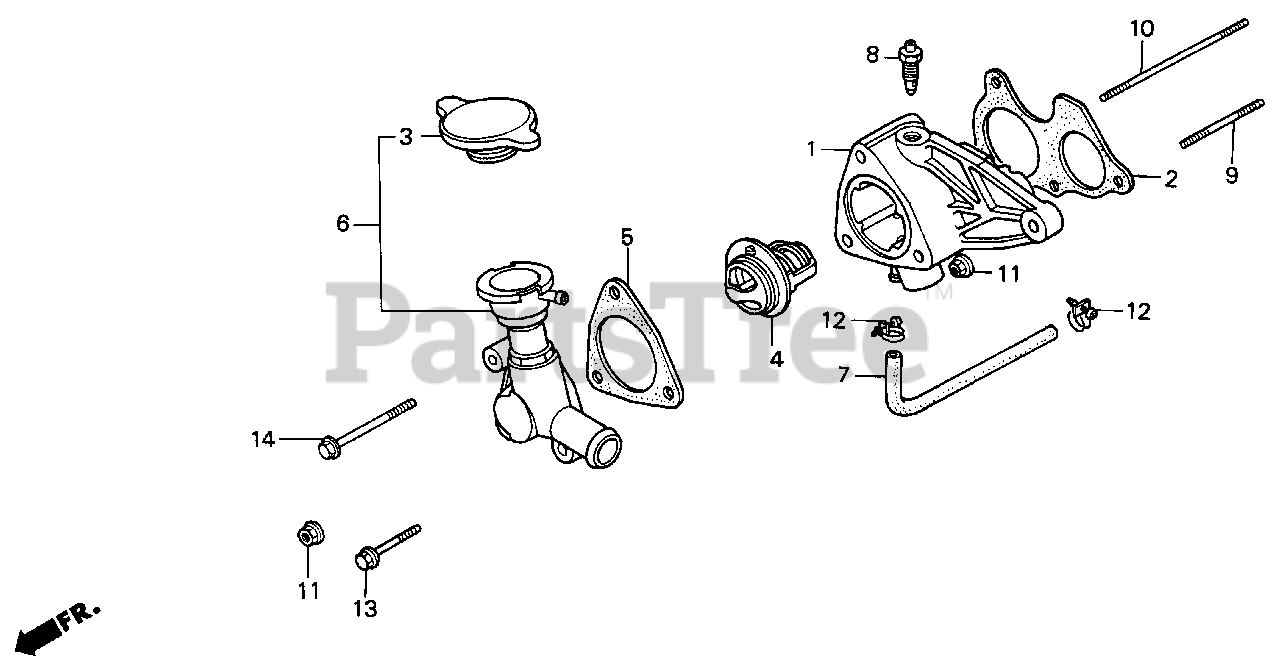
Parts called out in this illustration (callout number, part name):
1	CASE, THERMOSTAT
2	GASKET, GOVERNOR CASE
3	CAP, RADIATOR (DENSO)
4	THERMOSTAT ASSY.
5	GASKET, THERMOSTAT COVER
6	COVER, THERMOSTAT
7	HOSE, WATER BYPASS
8	BOLT, BREATHING WATER
9	BOLT, STUD (6X25)
10	BOLT, STUD (6X60)
11	NUT, FLANGE (6MM)
12	CLIP, TUBE (A13)
13	BOLT, FLANGE (6X65)
14	BOLT, FLANGE (6X90)
